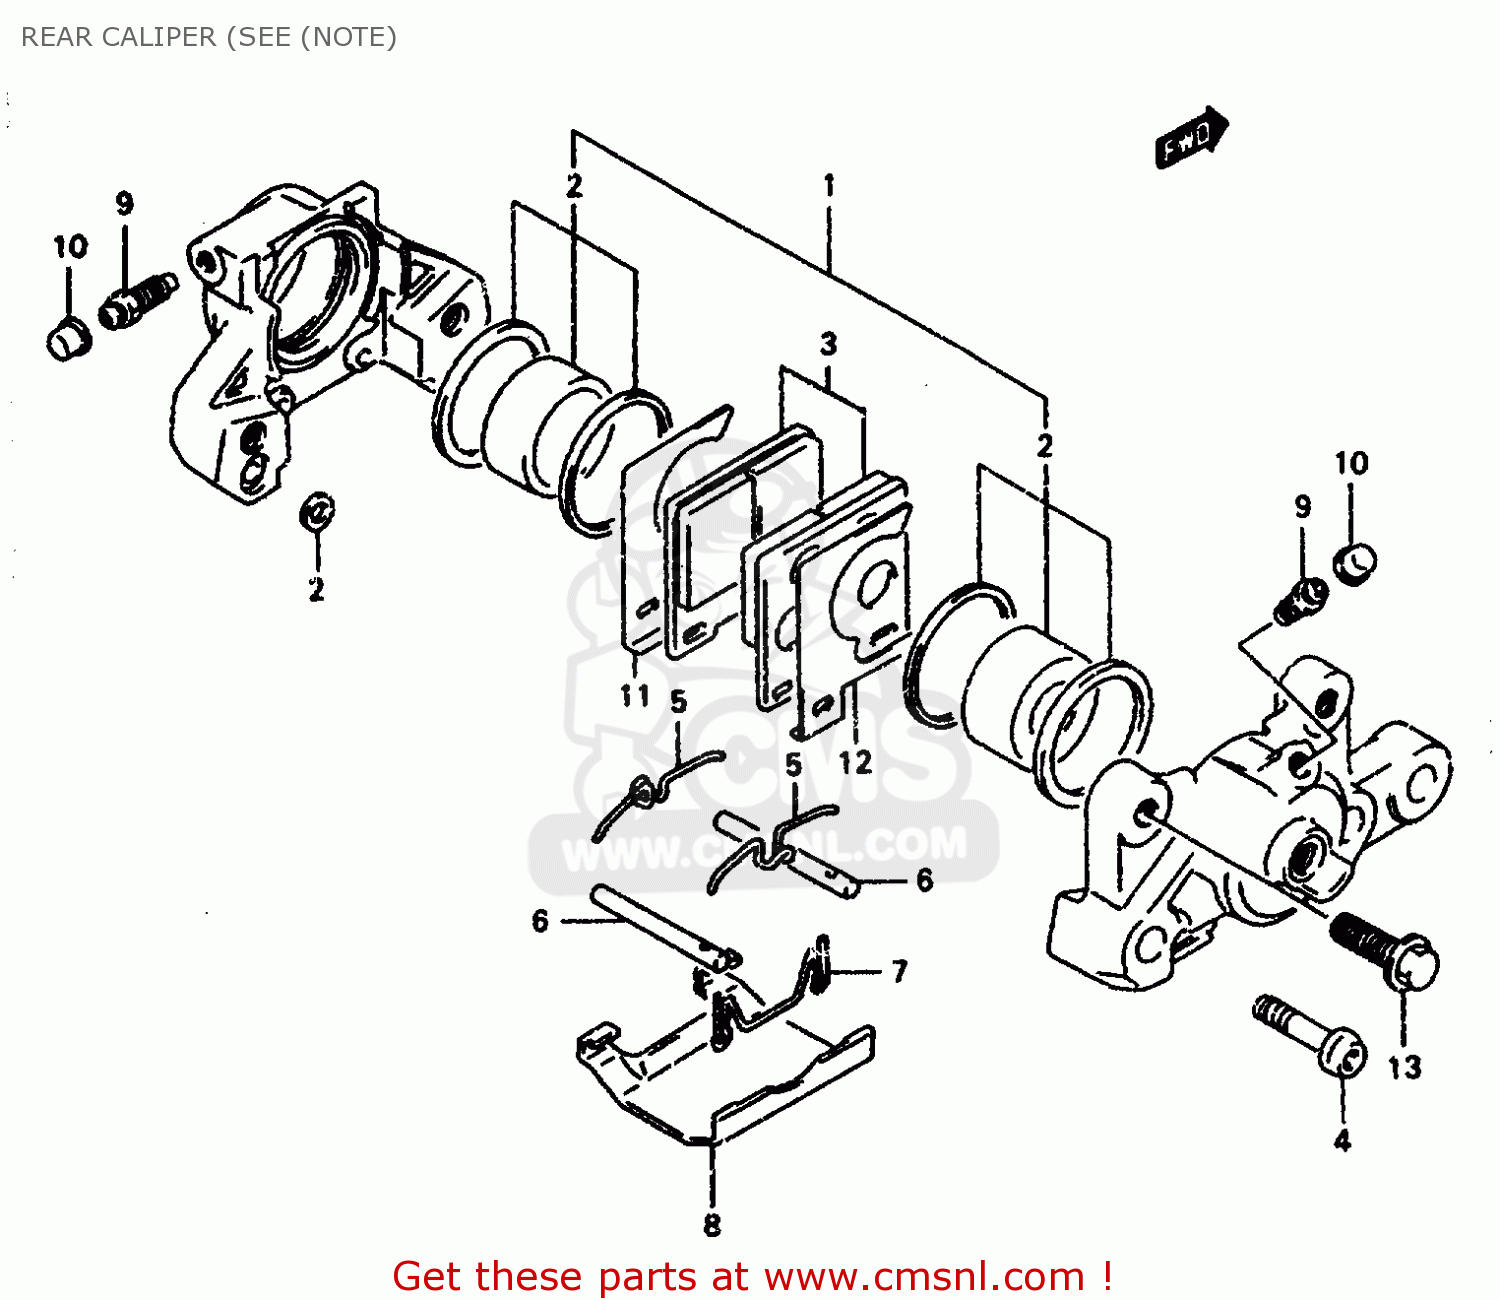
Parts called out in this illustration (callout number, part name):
1	PISTON SET
2	SEAL SET,PISTON
3	PAD SET (NAS)
4	BOLT,HOUSING
5	SPRING
6	PIN,PAD
7	CLIP,PAD PIN
8	COVER
9	BLEEDER
10	CAP,BLEEDER PLUG
11	SHIM,INNER
12	SHIM,OUTER
13	BOLT
14	SHIM,OUTER
15	BOLT
